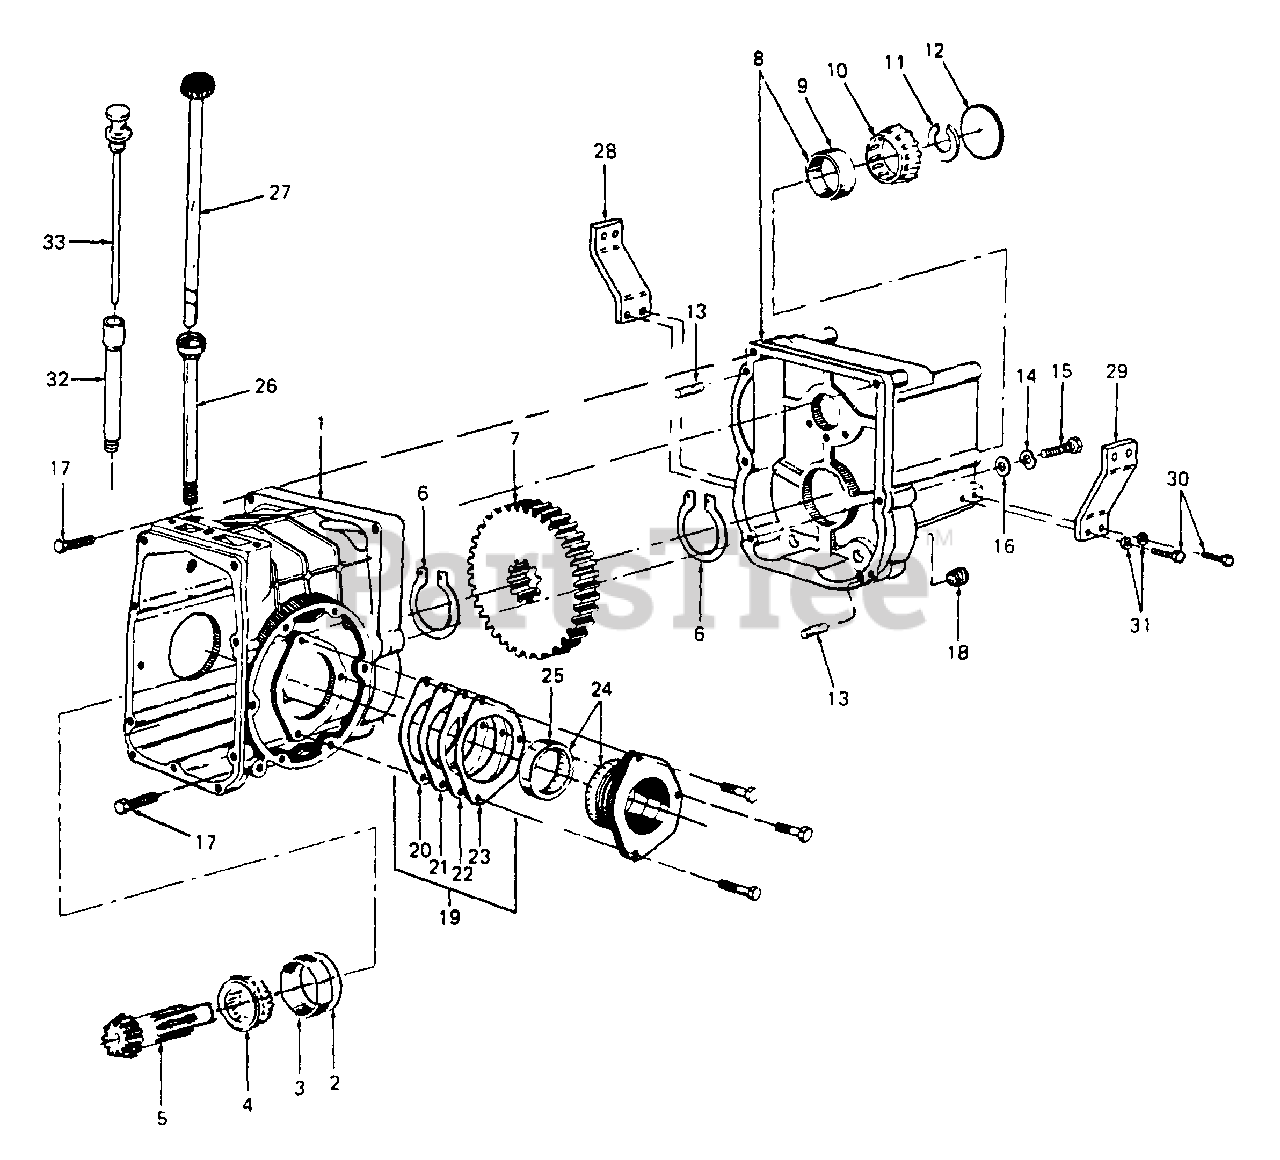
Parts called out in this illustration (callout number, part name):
1	Housing Assy, Rear Transaxle
2	Shim, Rear Bearing Cup, .004 Thk
3	Cup, Roller Bearing
4	Cone, Roller Bearing
5	Shaft, Bevel Pinion
6	Ring, Retaining, 1.312 Dia
7	Gear, Reduction - 68T
8	Housing Assy, Adapter w/Cup
9	Cup, Roller Bearing
10	Cone, Roller Bearing
11	Retainer, Front Bearing, .125 Thk
12	Plug, Expansion, 2.12 OD
13	Pin, Dowel, 3/8 Dia x 5/8 Lg
14	Washer, Spring, .445 x .75 x .017 Thk
15	Screw, Hex Cap, 7/16-14 x 2.5 Lg GR5
16	Washer, Flat, .46 x .875 x .060 Thk
17	Bolt, Hex Patch, 7/16-14 x 1.75 Lg GR5
18	Plug, Drain
19	Shim Package
20	Shim, Bearing Retainer, .004 Thk
21	Shim, Bearing Retainer, .007 Thk
22	Shim, Bearing Retainer, .014 Thk
23	Shim, Bearing Retainer, .028 Thk
24	Retainer Assy, Bearing w/Cup
25	Cup, Roller Bearing
26	Tube, Dipstick
27	Blade Assy, Dipstick
28	Bracket, Trans Mtg - LH
29	Bracket, Trans Mtg - RH
30	Bolt, Hex Patch, 3/8-16 x 1.0 LG GR5
31	Washer, Lock, 3/8
32	Tube, Dipstick
33	Blade Assy, Dipstick
